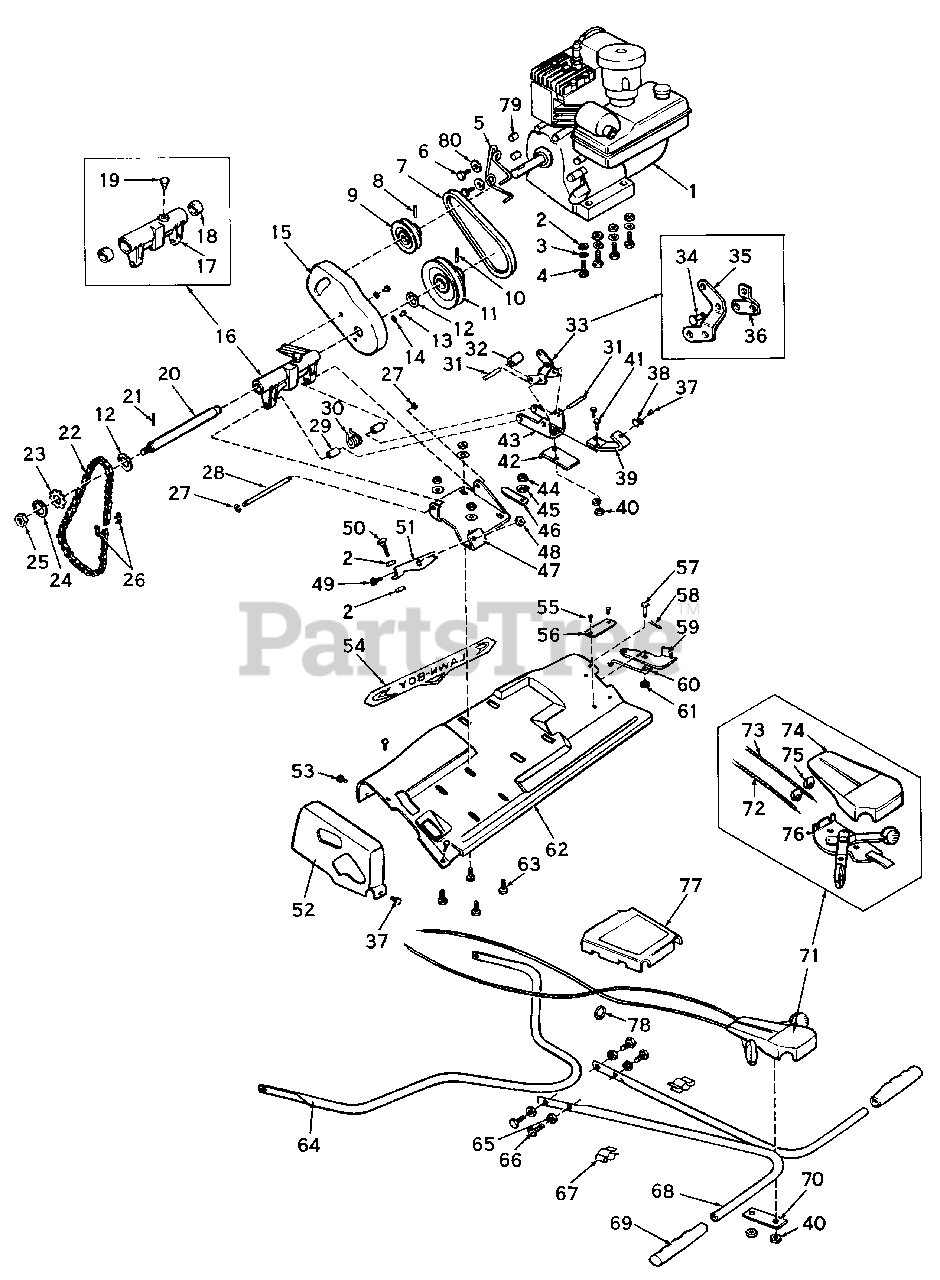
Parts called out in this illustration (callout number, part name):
1	Engine for 1041-0-18"
1	Engine for 1051-0-21"
2	Nut (5/16-18 Hex.)
3	Lockwasher (5/16)
4	Bolt (5/16-18 x 1-3/8 Carriage)
5	Keeper-18"
5	Keeper-21"
6	Screw (1/4-20 x 1-3/4 Hex. Hd.)
7	"V" Belt
8	Screw (5/16-24 x 7/32)
9	Pulley-18"
9	Pulley-21"
10	Roll Pin
11	Pulley Assembly
12	Washer (5/8 x 5/16)
13	Screw (#10-32 x 1/2 Sems Ph. Hd. Thd Cut.)
15	Belt Guard
16	Jackshaft Housing, Bearings and Oiler Assembly
17	Jackshaft Housing
18	Bearing
20	Jackshaft
23	Sprocket
24	Washer
25	Nut (5/16-20 Hex. Jam Lock.) (Gripco)
26	Connector Link
27	Retaining Ring
31	Roll Pin
33	Roller Lever Assembly
34	Rivet
35	Roller Lever-L.H.
36	Roller Lever-R.H.
37	Screw (#10-32 x 3/8 Ph. Rd. Hd. Thd. Cut. Sems)
39	Control Bracket
40	Nut (#10-32 Gripco)
41	Screw (#10-32 x 9/16 Rd. Hd. Sems)
44	Nut (1/4-20 Hex.)
45	Lockwasher (1/4)
48	Nut (5/16-24 Hex. Lock. Gripco)
49	Bolt (5/16-24 Hex. Shoulder Bolt)
50	Bolt (5/16-18 x 1-5/8 Step)
53	Screw (5/16-24 x 1/2 Sems Pan. Hd.)
54	Lawn-Boy Label
55	Screw (#6 x 1/4 Rd. Hd. Ph. Self Tapping)
56	Name Plate-18"
56	Name Plate-21"
57	Clevis Pin
58	Cotter Pin
61	Washer
63	Bolt (1/4-20 x 5/8)
64	Lower Handle Section-18"
64	Lower Handle Section-21"
65	Nut (1/4-20 Hex.)
66	Bolt (1/4-20 x 1-1/4 Hex.)
68	Upper Handle Section
69	Handle Grip
71	Dual Throttle Control Assy.
72	Throttle Control Cable
73	Insta-Control Cable
74	Control Cover
76	Control Assembly
77	Handle Cover and Label
